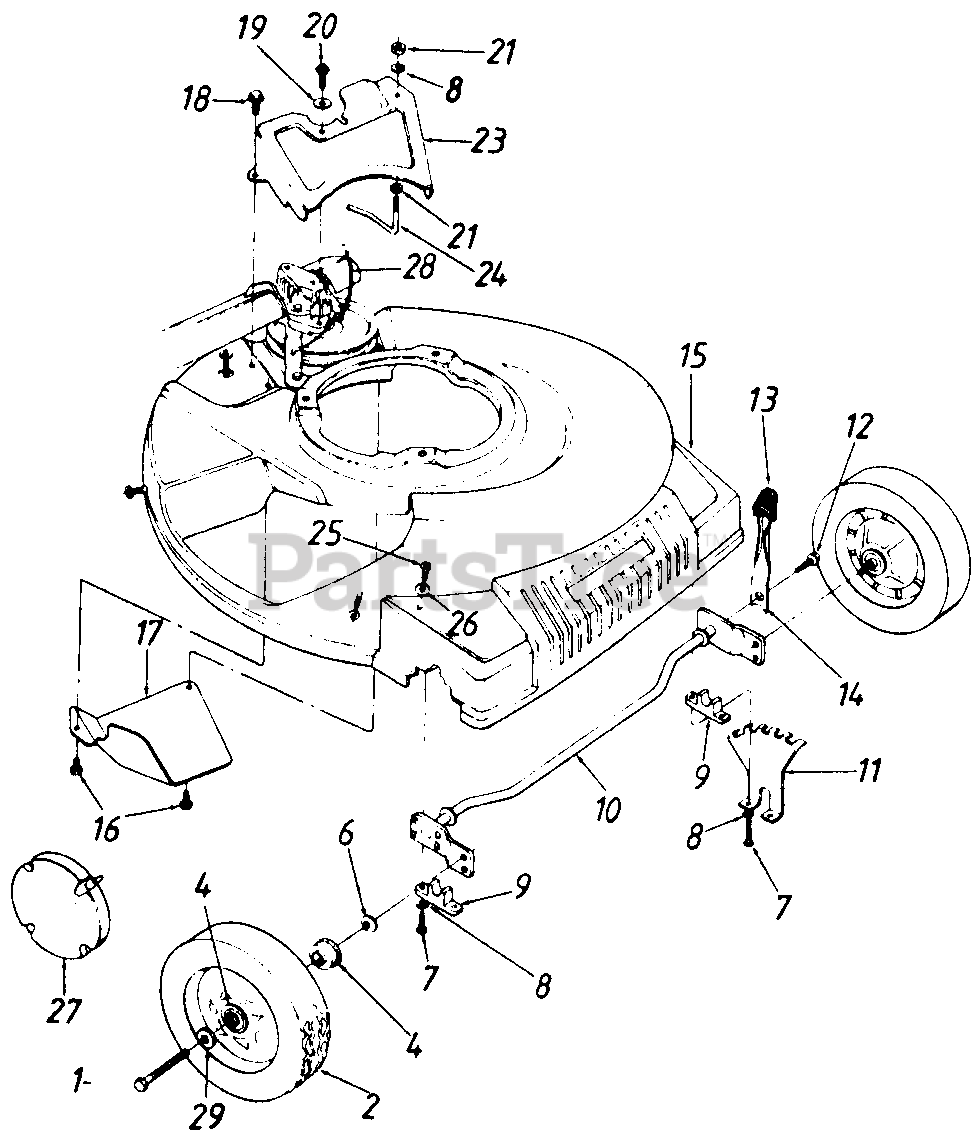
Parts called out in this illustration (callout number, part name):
1	Front Axle Bolt
2	Wheel Ass'y. Comp. 8 x 2"
4	Flange Ball Brg. .501" I.D.
6	Bell-Wash. .345" I.D. x .88
7	Hex Wash. Hd. B-Tap Scr. 1/4-20
8	L-Wash. 1/4" I.D.
9	Block Bushing
10	Axle Ass'y.
11	Height Adj. Bracket
12	Hex Wash. Hd. TT-Tap Scr. 1/4-20 x .5" Lg.
13	Knob
14	Spring Lever
15	Plastic Front End
16	Hex B-Tap Scr. 1/4-.38"
19	Bell-Wash. .265" I.D. x .75"
20	Hex Wash. Hd. B-Tap Scr. 1/4 x.62"
21	Hex Nut 1/4-20 Thd.
23	Transmission Belt Guard
24	S.P. Belt Guard
25	Truss B-Tap Scr. 5/16 x .75"
26	Bell-Wash. 5/16" I.D. x 5/8
27	Hub Cap
28	S.P. Cable 50" Lg.
29	Fl-Wash. .531" I.D.
